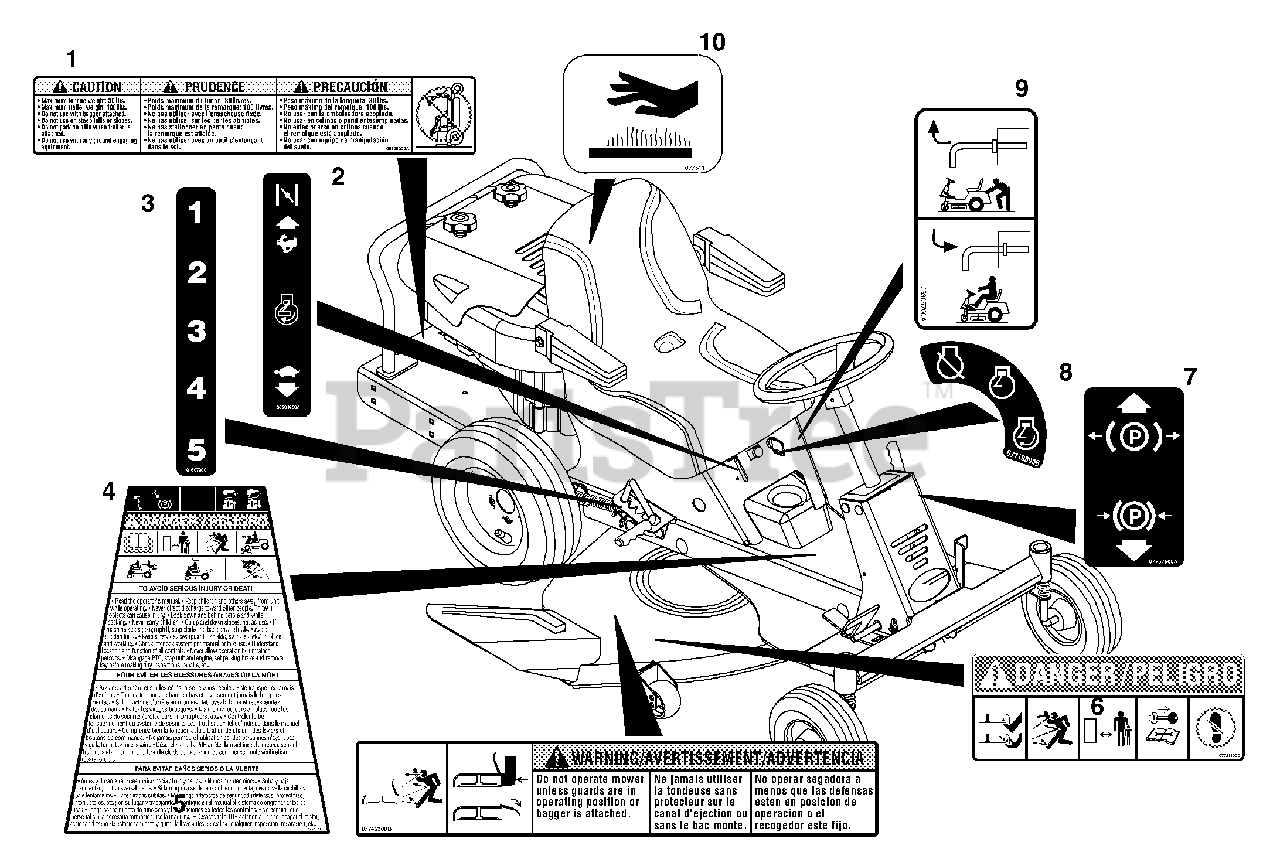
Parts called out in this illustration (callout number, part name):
1	DECAL-HITCH 100#
2	DECAL-THROTTLE RER/SPORT
3	DECAL, 5 POSITION CUT HEIGHT
4	DECAL-RER WARNING
5	DECAL, WARNING
6	DECAL, MOWER PAN DANGER
7	DECAL, PARKING BRAKE LEVER
8	DECAL - IGNITION
9	DECAL, TRANS DISCONNECT
10	DECAL, HOT SURFACE
